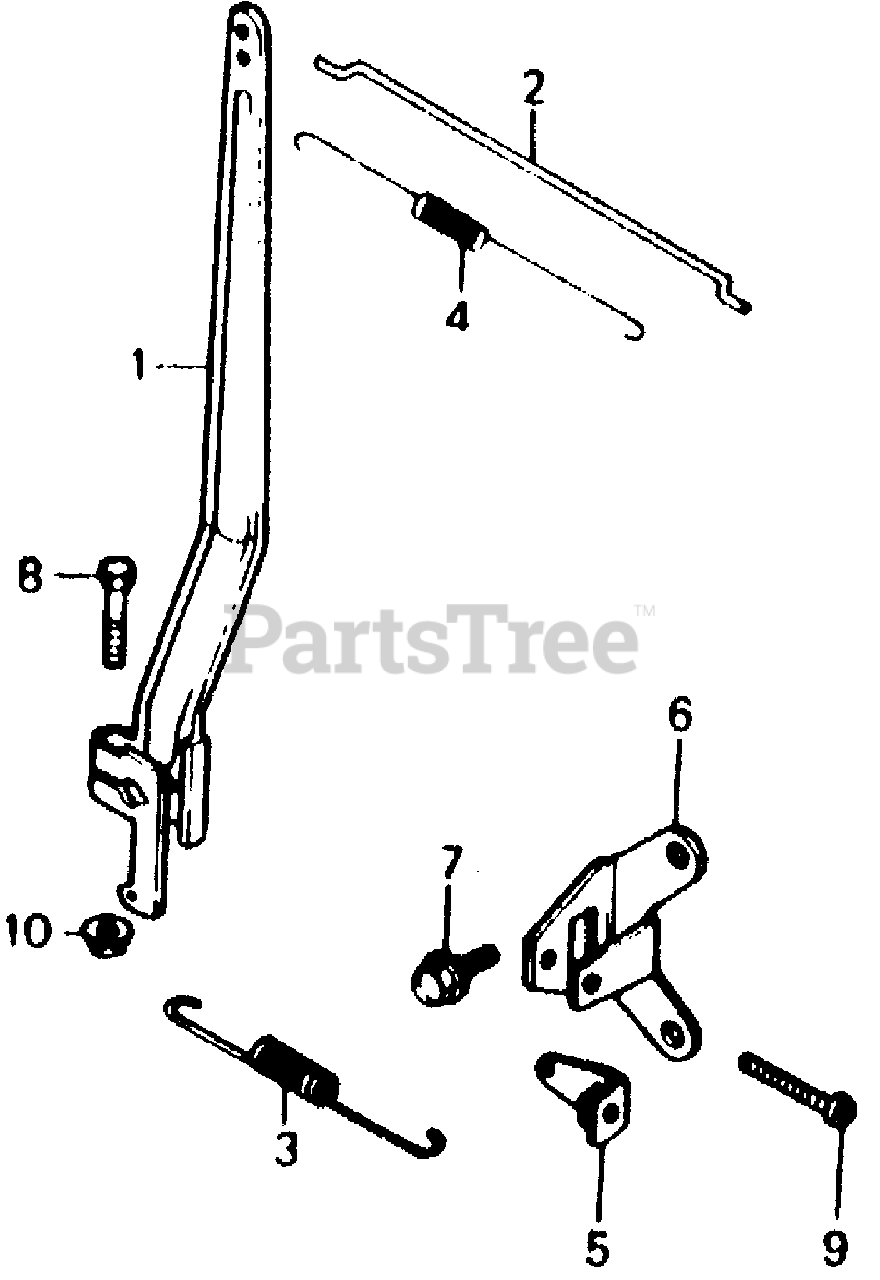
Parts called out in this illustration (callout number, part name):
1	ARM, GOVERNOR
2	ROD, GOVERNOR
3	SPRING, GOVERNOR
4	SPRING, THROTTLE RETURN
5	PLATE, CONTROL (NOT AVAILABLE)
6	BASE, CONTROL
6	BASE, CONTROL (NOT AVAILABLE)
7	BOLT, FLANGE (6X12) (CT200)
8	BOLT, HEX. (6X25)
9	SCREW, PAN (6X25)
10	NUT, FLANGE (6MM)
